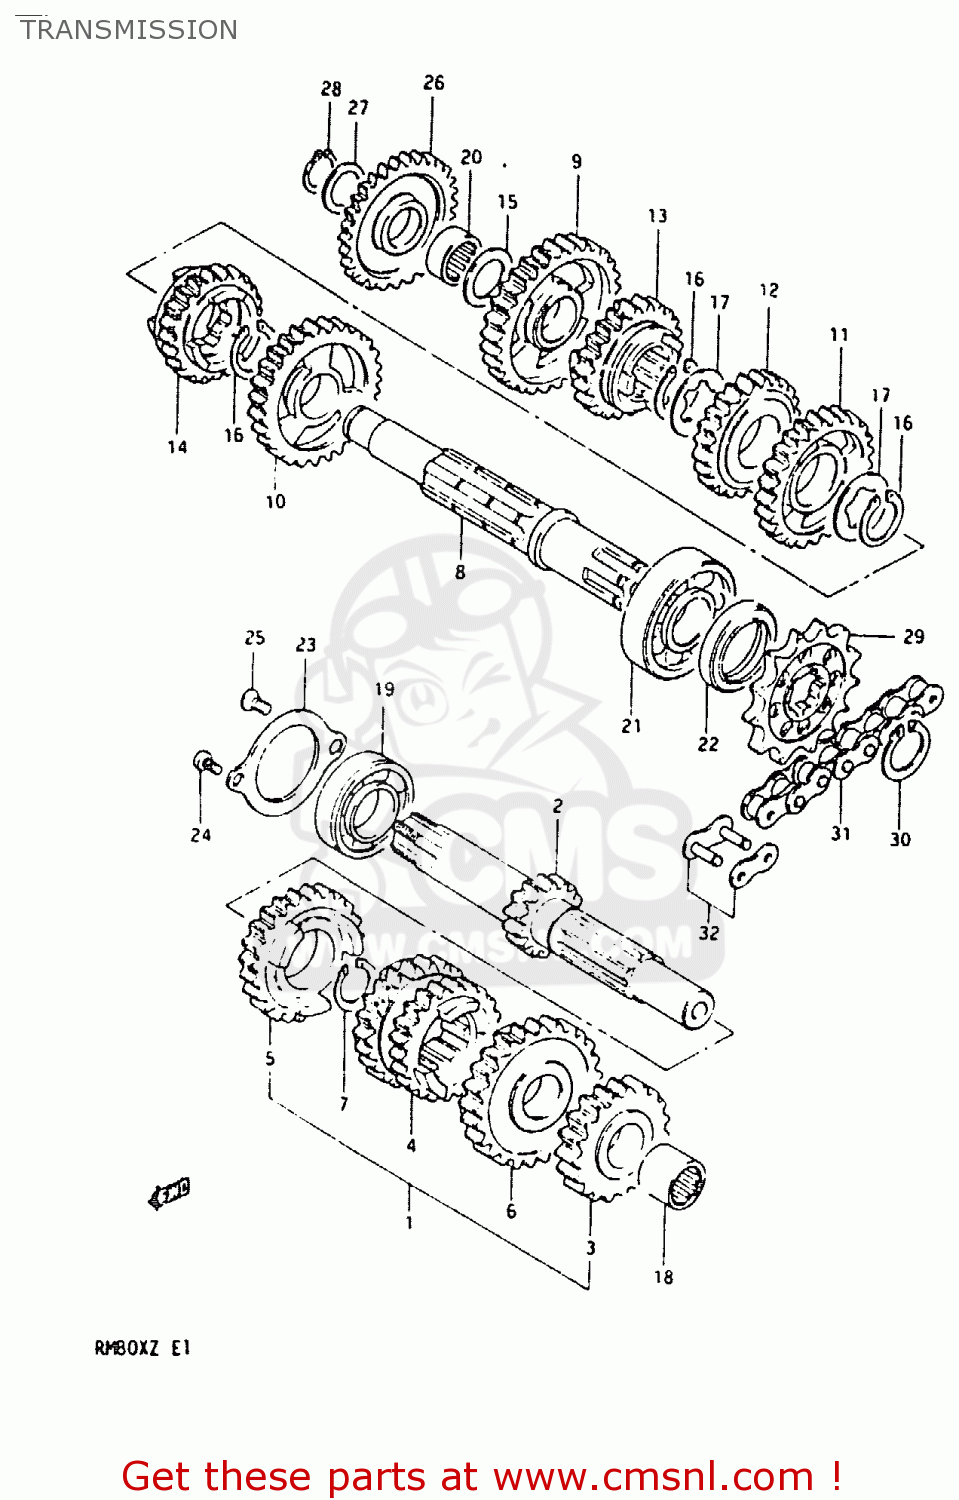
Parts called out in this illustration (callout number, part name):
1	SHAFT,COUNTER
2	SHAFT,COUNTER
3	GEAR,SECOND DRIVE
4	GEAR,THIRD/FOURTH DRIVE
5	GEAR,FIFTH DRIVE
6	GEAR,SIXTH DRIVE
7	CIRCLIP
8	SHAFT,DRIVE
9	GEAR,FIRST DRIVEN
10	GEAR,SECOND DRIVEN
11	GEAR,THIRD DRIVEN
12	GEAR,FOURTH DRIVEN
13	GEAR,FIFTH DRIVEN
14	GEAR,SIXTH DRIVEN
15	WASHER
16	CIRCLIP
17	WASHER,LOCK
18	ROLLER BEARING (13X19X1
19	BEARING
20	BEARING(15X21X12)
21	Bearing
22	OIL SEAL (20X35X5)
23	RETAINER,CNTR SHAFT BEARING
24	SCREW
25	SCREW
26	GEAR,KICK STARTER IDLE
27	THRUST WASHER
28	CIRCLIP
29	SPROCKET,ENGINE
30	CIRCLIP
31	CHAIN,DRIVE #428HM-11
32	JOINT SET,CHAIN
